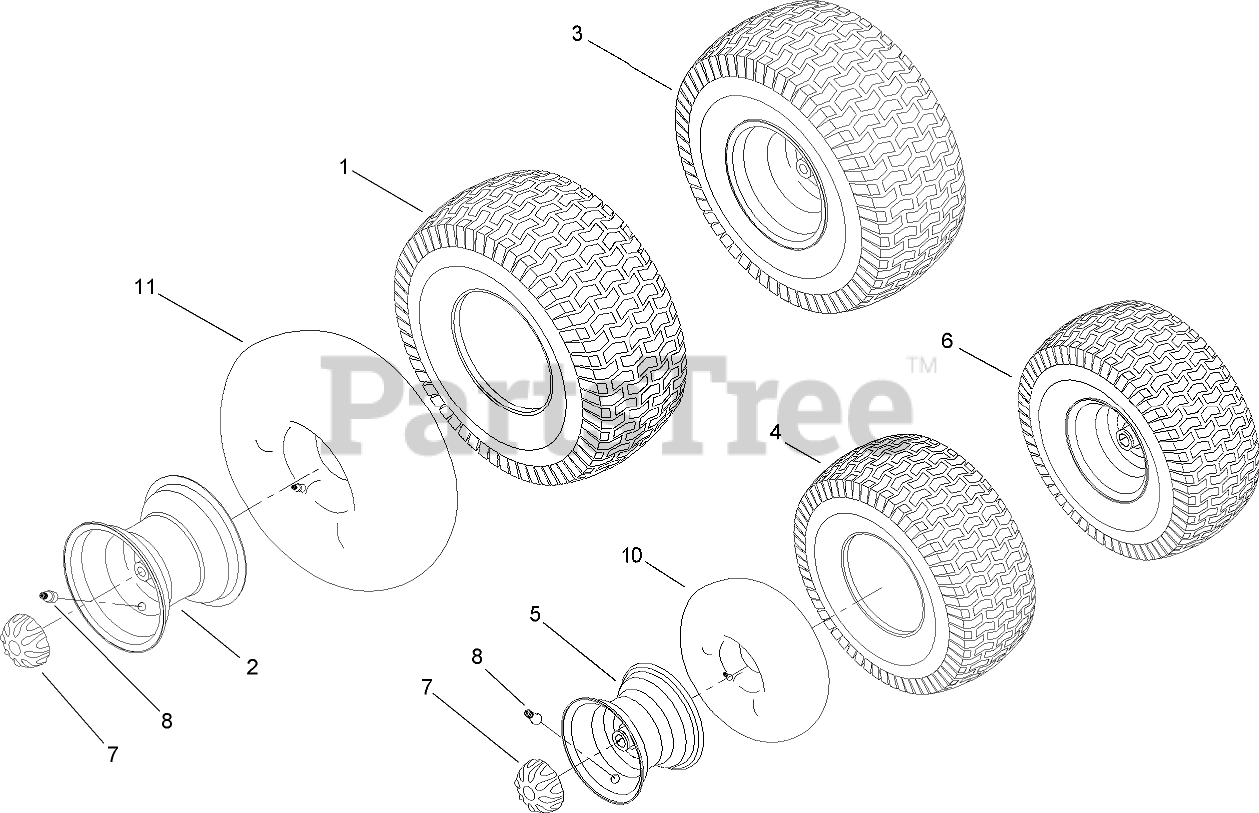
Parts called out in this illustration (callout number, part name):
1	TIRE-TURF
2	RIM-WHEEL, Rear
3	WHEEL ASM
4	TIRE-TURF
5	Rim-Wheel, Front
6	WHEEL ASM
7	CAP-HUB
8	VALVE-AIR, TUBELESS
10	TUBE-INNER
11	TUBE-INNER
